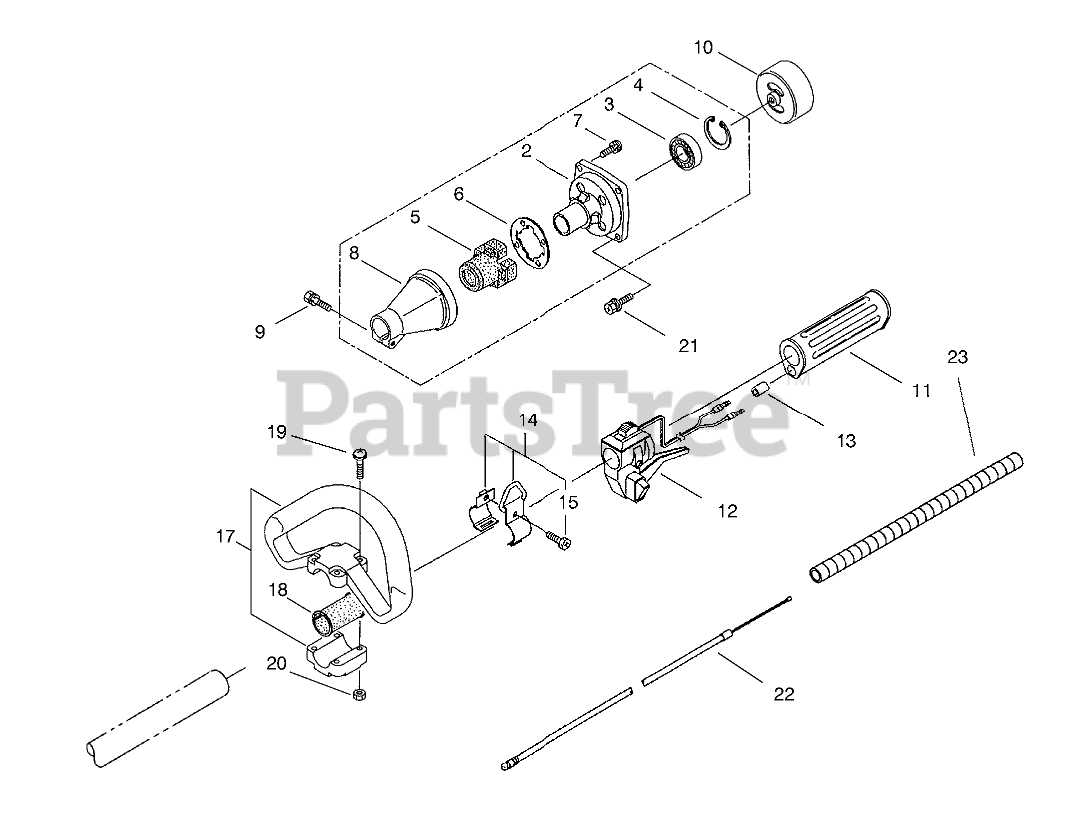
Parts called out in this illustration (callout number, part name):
2	CASE - BEARING
3	BEARING
4	RING - SNAP
5	BUFFER
6	WASHER
7	SCREW
8	ADAPTER-DRIVESHAFT TUBE
10	DRUM - CLUTCH
11	GRIP - SHAFT
12	TRIGGER - THROTTLE
13	GUIDE - OUTER
14	Hanging Bracket Assembly (Incl. Ref. #15)
17	HANDLE - LOOP
18	PACKING
19	SCREW
20	NUT M5
22	CABLE - THROTTLE
23	TUBE - PLASTIC
